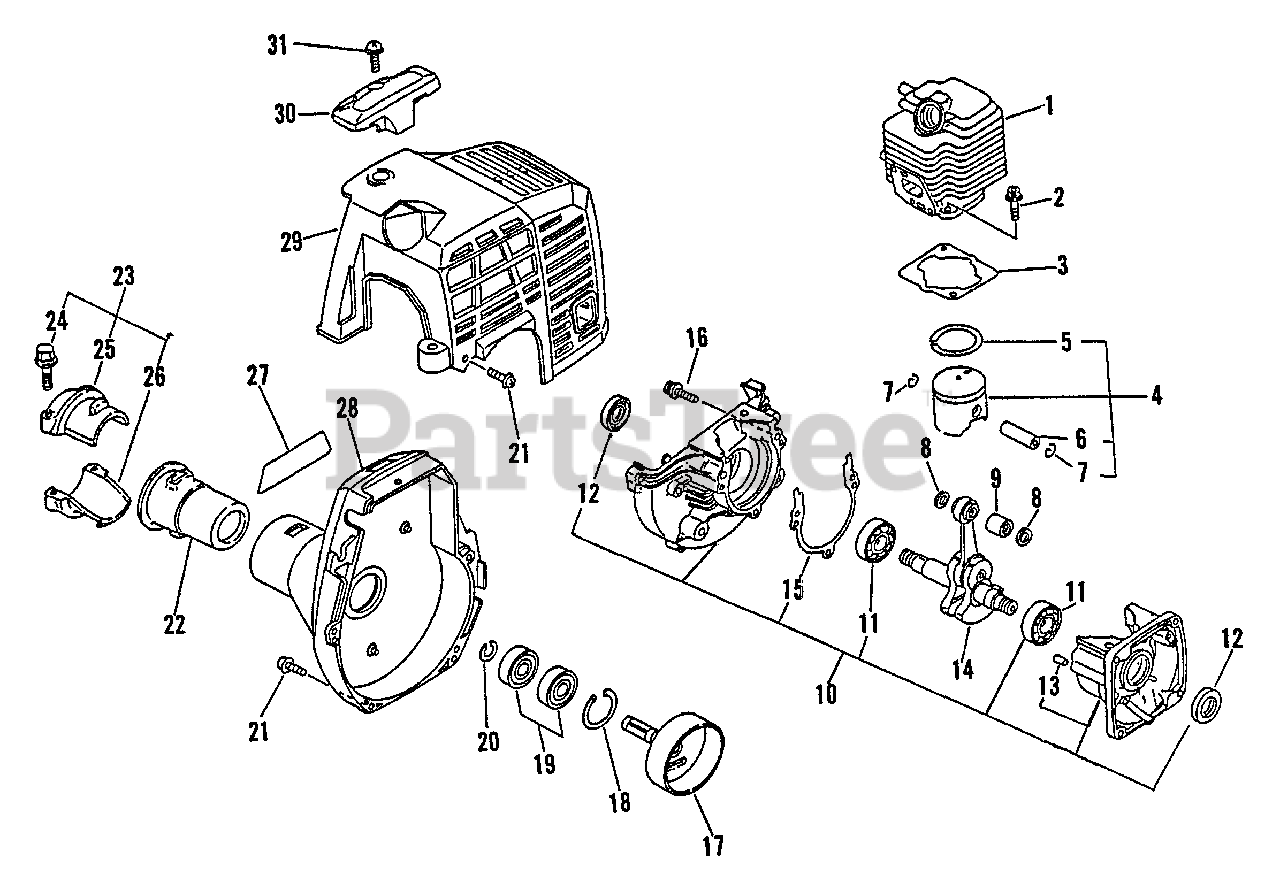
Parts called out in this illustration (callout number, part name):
1	Cylinder
2	Bolt, H.S. 5X22
3	Gasket, Cylinder Base
4	Piston kit
5	Ring, Piston
6	Pin, Piston
7	Circlip, Piston Pin
8	Spacer, Piston Pin
9	Bearing, Needle
10	Crankcase Kit
11	Bearing, Ball 6201
12	Oilseal
13	Pin, Dowel
14	Crankshaft
15	Gasket, Crankcase
16	Screw 5X28
17	Drum, Clutch
18	Circlip 28
19	Bearing, Ball 6001
20	Circlip 12
21	Screw 4X16
23	Holder Kit
24	Bolt 5X25
27	Label, Model
28	Cover Asy, Fan
29	Cover Cylinder
30	Guard, Top
31	Screw 5X16
